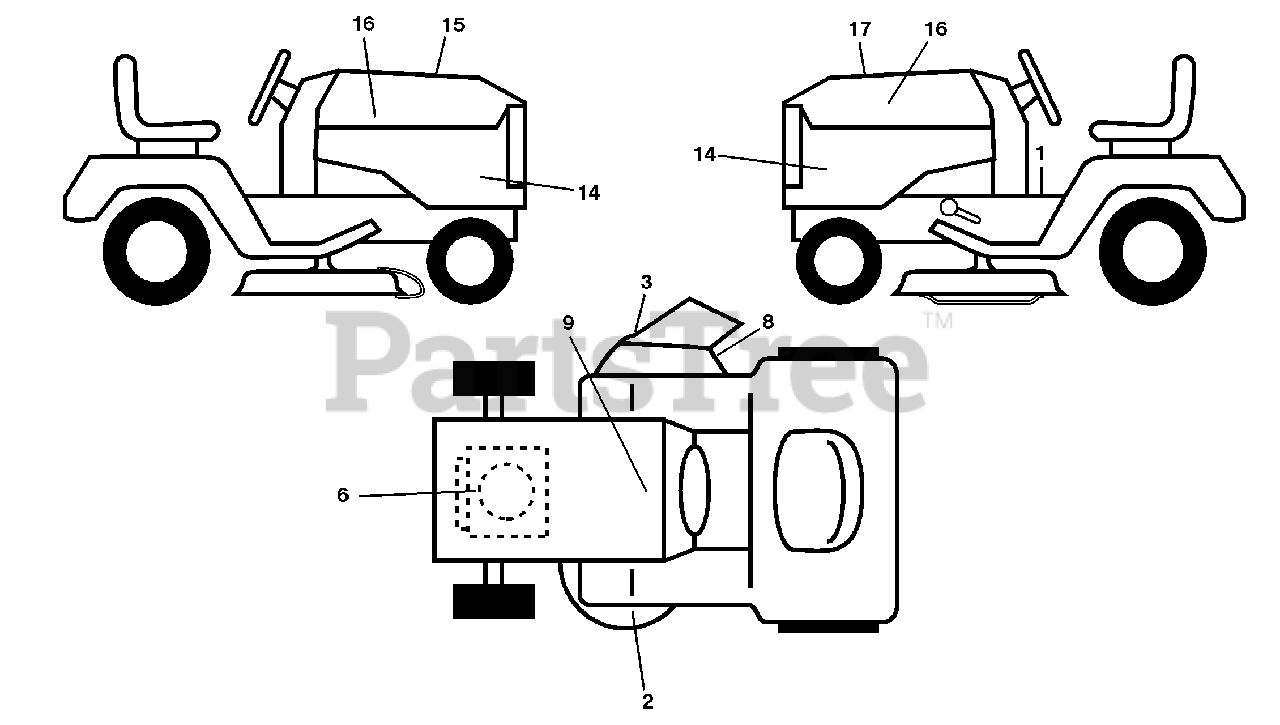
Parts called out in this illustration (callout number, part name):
1	Decal, Operator’s
2	Decal, Deck Airinduct
3	Decal, Warning
6	Decal, Eng. H.P.
8	Decal, Mower Sch.
9	Decal, Battery Dnge/Poi
14	Decal, Panel Side
15	Decal, Cust. Resp.
16	Decal, Hood Logo
17	Decal, Replacement
17	Decal, Bypass
17	Pad, Footrest, LH
17	Pad, Footrest, RH
17	Manual, Owner’s
